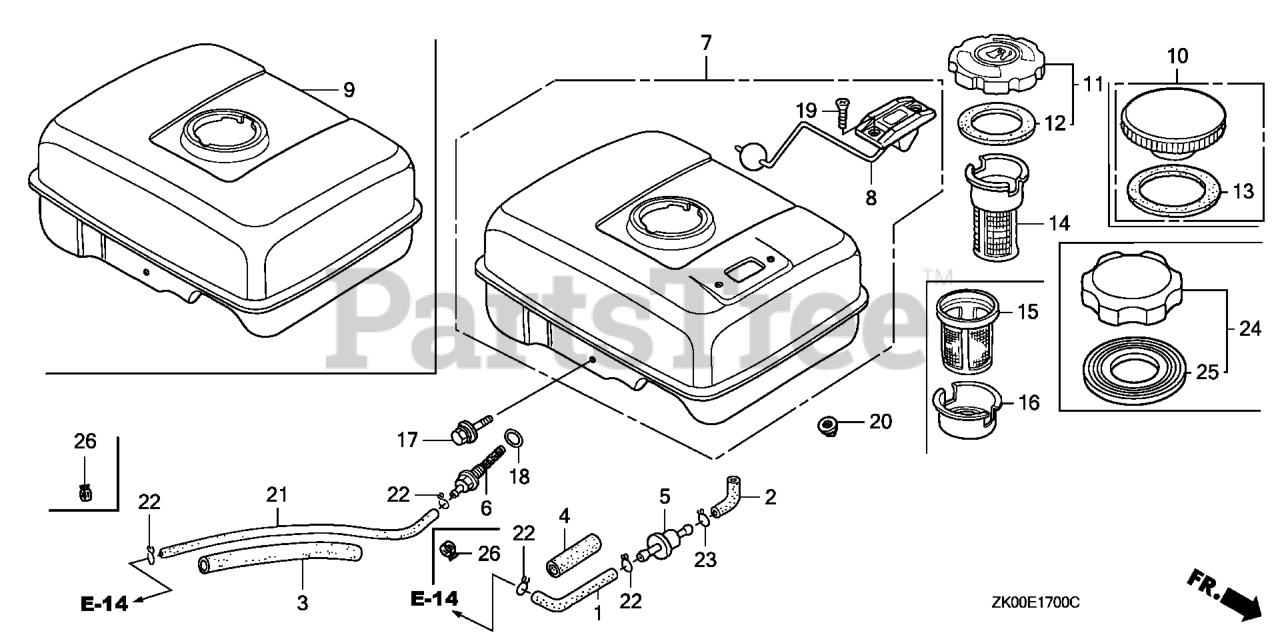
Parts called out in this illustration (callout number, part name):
3	RUBBER, SUPPORTER (107MM)
6	JOINT, FUEL TANK
9	TANK, FUEL *NH31* (MCKINLEY WHITE) Use up to Engine SN 3033315.
9	TANK, FUEL *NH1* (BLACK)
17	BOLT, FLANGE (6X34)
18	O-RING (14MM) (ARAI) Use up to Engine SN 2949254.
20	NUT, FLANGE (6MM)
21	BULK HOSE, FUEL (4.5X3000) (Honda Code 5137104). (4.5X140)
22	CLIP, TUBE (B8)
24	CAP, FUEL FILLER (CHROME PLATED)
25	GASKET, FUEL FILLER CAP (39X62X3) (TOUYOUSYA)
